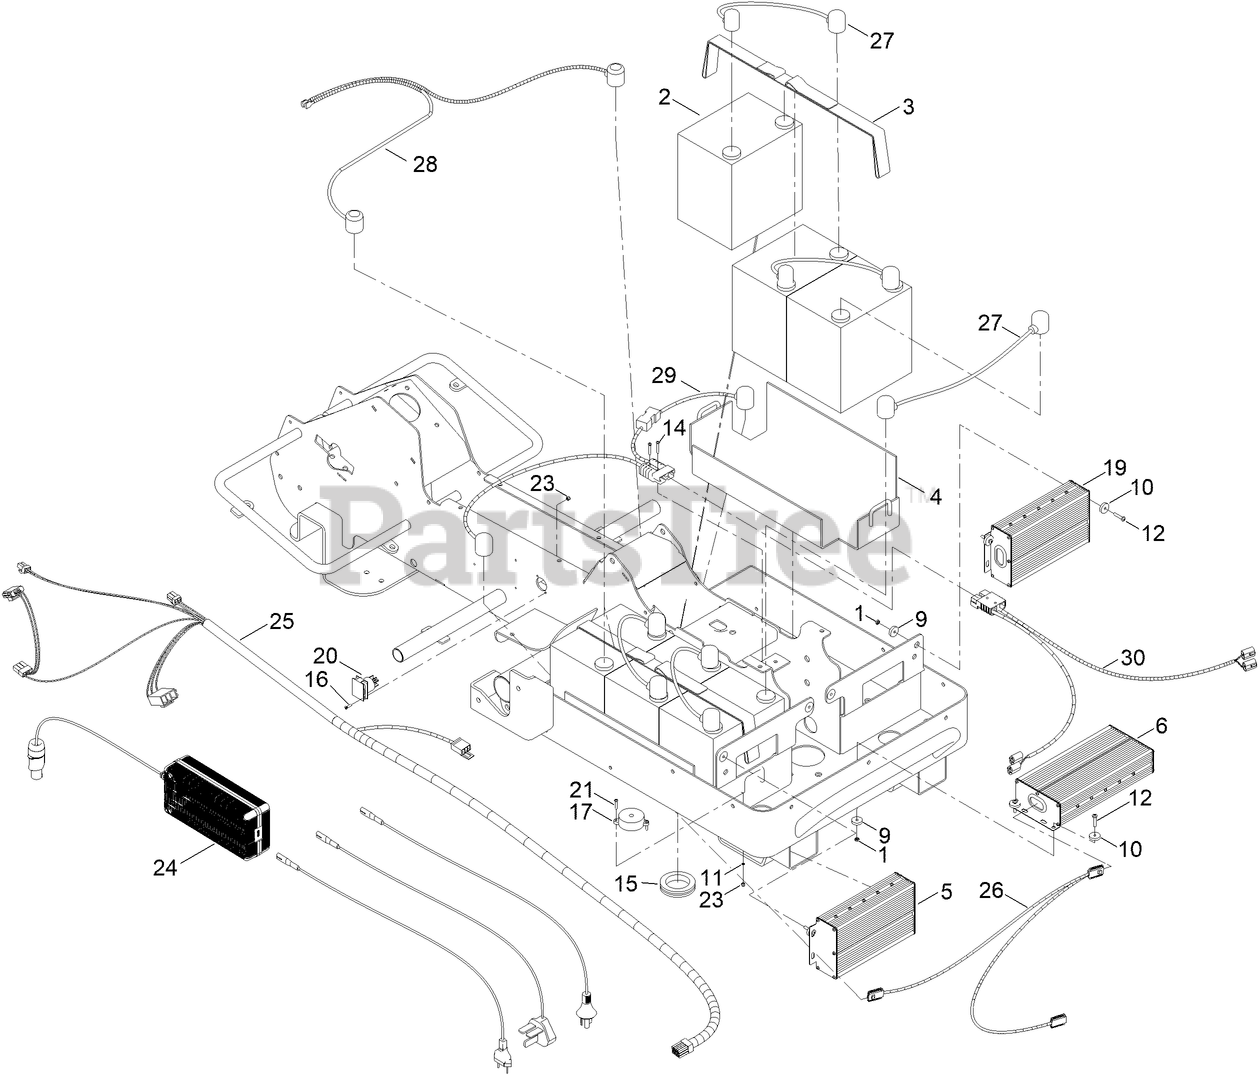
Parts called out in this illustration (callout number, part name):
2	BATTERY
3	STAP, BATTERY
4	HOLDER, BATTERY
5	CUTTING CONTROLLER
6	DRIVING CONTROLLER
9	FLAT BUSH, RUBBER
10	BUSH, RUBBER
11	SPRING WASHER
15	INSERT, RUBBER CABLE LARGE
19	CUTTING CONTROLLER
20	POWER CONNECTOR ASM
23	NUT-NYLOC
24	CHARGER
25	WIRING HARNESS, SENSORS
26	WIRING HARNESS, CONTROLER CONNECTOR
27	WIRING HARNESS, BATTERY CONNECTOR
28	WIRING HARNESS, BATTERY/CHARGING WIRE
29	WIRING HARNESS, FUSE WIRE
30	WIRING HARNESS, POWER CONNECTOR
